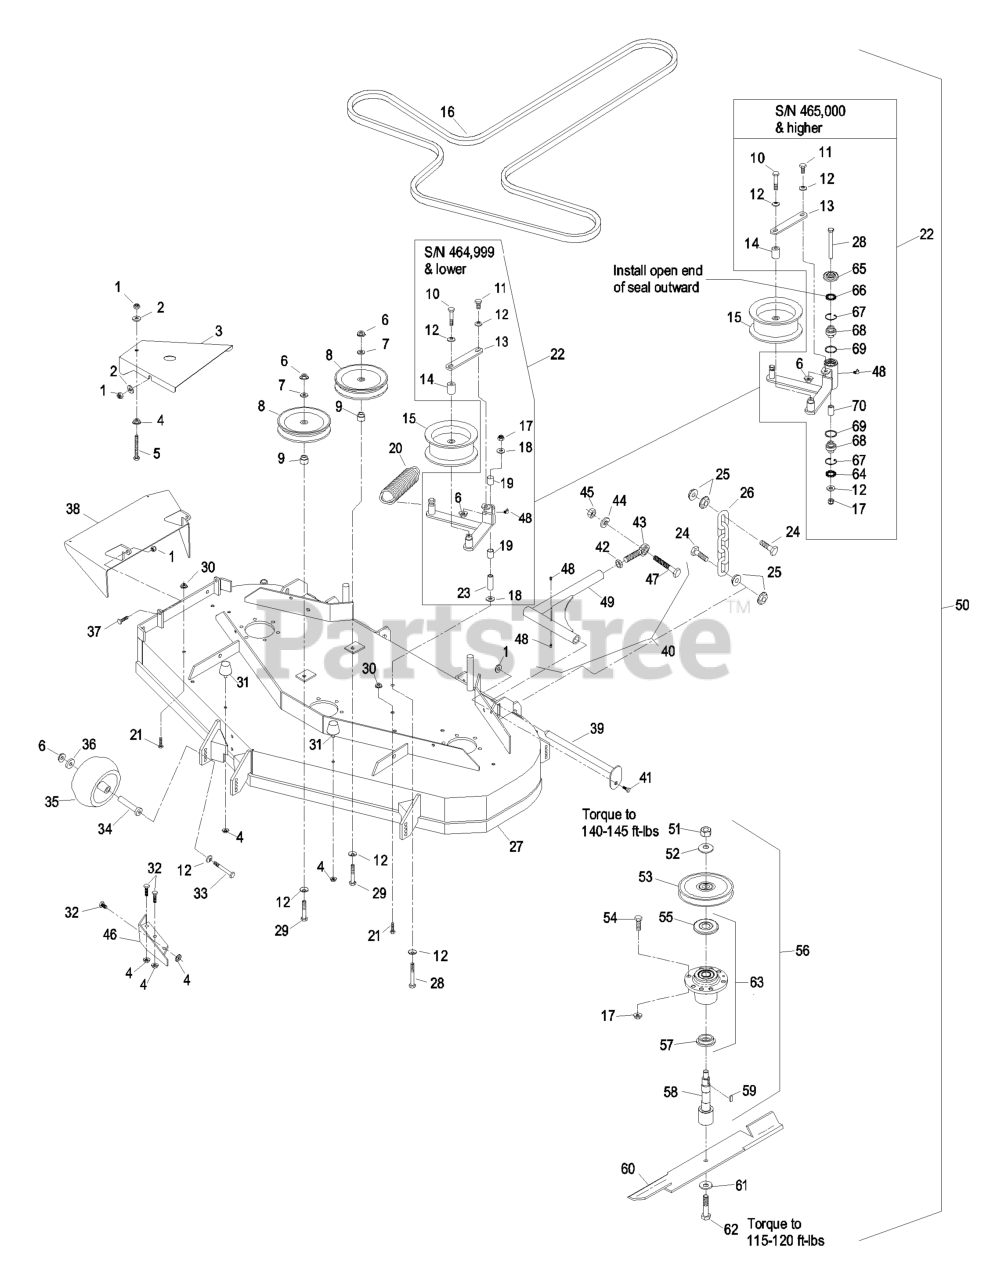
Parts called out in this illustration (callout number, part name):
1	NUT-LOCK, NI
2	WASHER-FLAT
3	SHIELD,BELT
5	BOLT,TAP HH
6	NUT-HHF, WHIZ
7	WASHER-FLAT
8	PULLEY-IDLER
9	BUSHING-IDLER
10	SCREW-HH
11	SCREW-HH
12	WASHER-BELLEVILLE
13	PLATE
16	BELT,BLADE DRIVE
17	NUT-LOCK, NI
18	WASHER-HARDENED
19	SLEEVE-BEARING
21	SCREW-HH
22	KIT,DECK IDLER LHP/LCT
23	BUSHING-PIVOT, IDLER
24	SCREW-HH
26	CHAIN-LIFT, DECK
28	SCREW-HH
29	SCREW-HH
31	BUMPER-RUBBER
32	SCREW-HH
33	SCREW-HH
34	BUSHING-ROLLER
35	ROLLER-SCALP, ANTI
37	SCREW-HH
38	WLD,DISCHARGE CHUTE
39	PIN-STRUT
40	STRUT ASM
41	SCREW-HH
42	NUT-HEX
43	BALLJOINT-SPHERICAL
44	WASHER-LOCK
45	NUT-HEX
46	WLD,BAFFLE DISCHARGE
48	FITTING-GREASE
50	Deck Complete Service
53	SHEAVE,6.13 EOD
54	SCREW-HH
55	GUARD-BEARING, TOP
57	SPACER-GUARD, BOTTOM
58	SPINDLE,LHP
59	KEY-RECTANGLE
61	WASHER-BLADE BOLT, HEAVY
62	SCREW-CAP
64	SEAL-LIP, DOUBLE
65	GUARD-TOP
66	SEAL-LIP, SINGLE
67	RING-SNAP
68	BEARING-SPHERICAL
69	O-RING
70	SPACER
